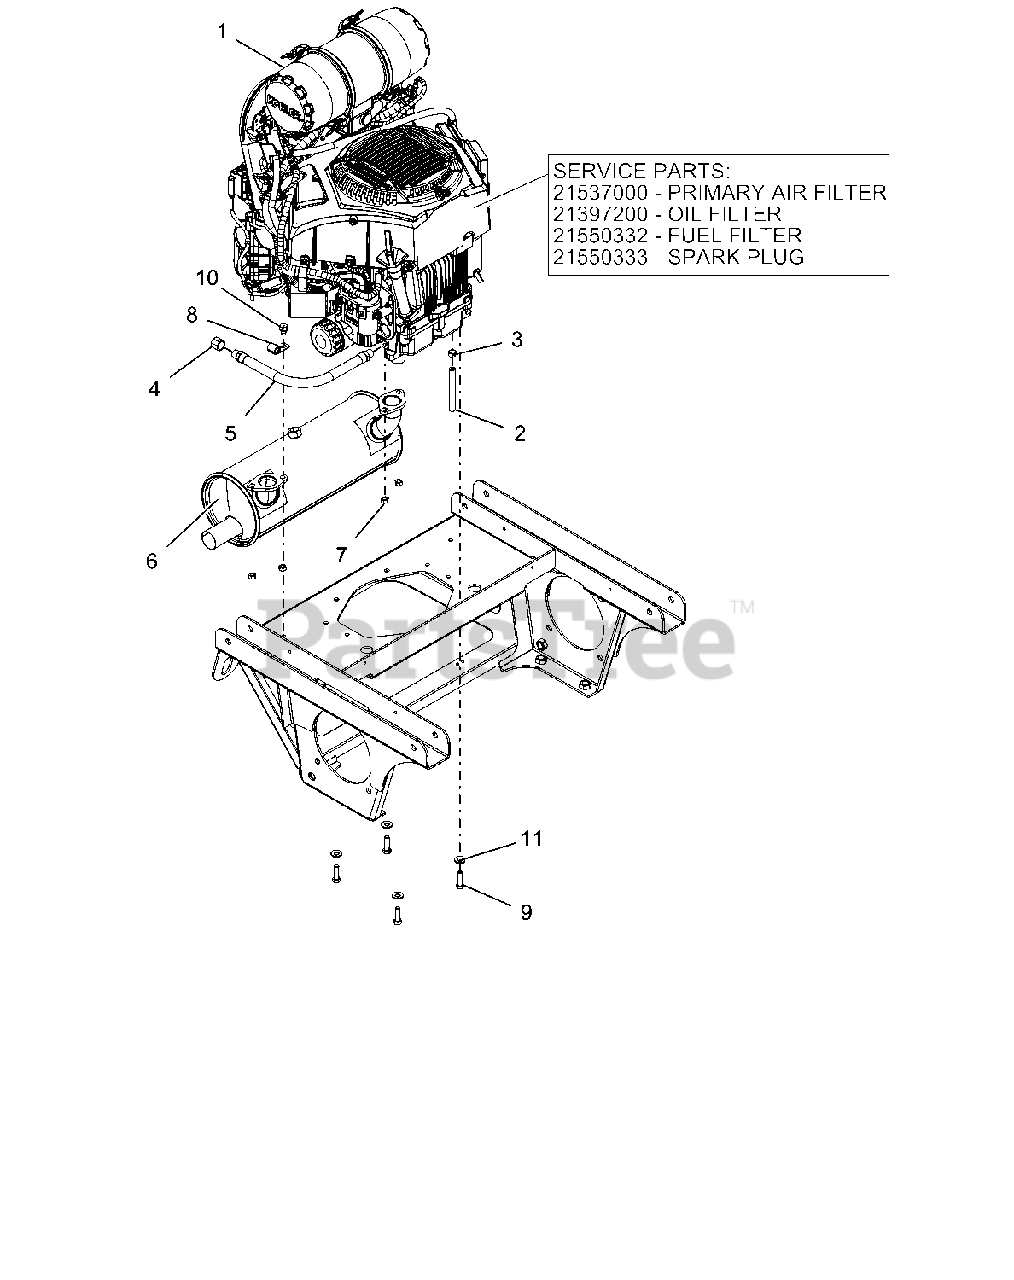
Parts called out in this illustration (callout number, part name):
1	FILTER, OIL - KOH CV20
1	ELEMENT, OUTER PRIMARY
1	ENGINE, KOHLER EFI
1	FILTER, FUEL-KOHLER EFI
1	PLUG, SPARK-KOHLER EFI
2	HOSE, .25 LOW-PERM BULK GAS
3	CLAMP, FUEL LINE
4	PIPE CAP 3/8 NPT FEMALE
5	HOSE,HYD .38-14-0K M6N0-M6N0
6	MUFFLER, KOHLER EFI
7	NUT-LK-TOP M8-1.25 YWZC
9	BLT-HEX.38-16X1.25 G5YZ NYTORQ
10	SCR-TAP .38-16X.50 HWH TR YWZ
11	WASHER, 3/8" SPRING DISC
